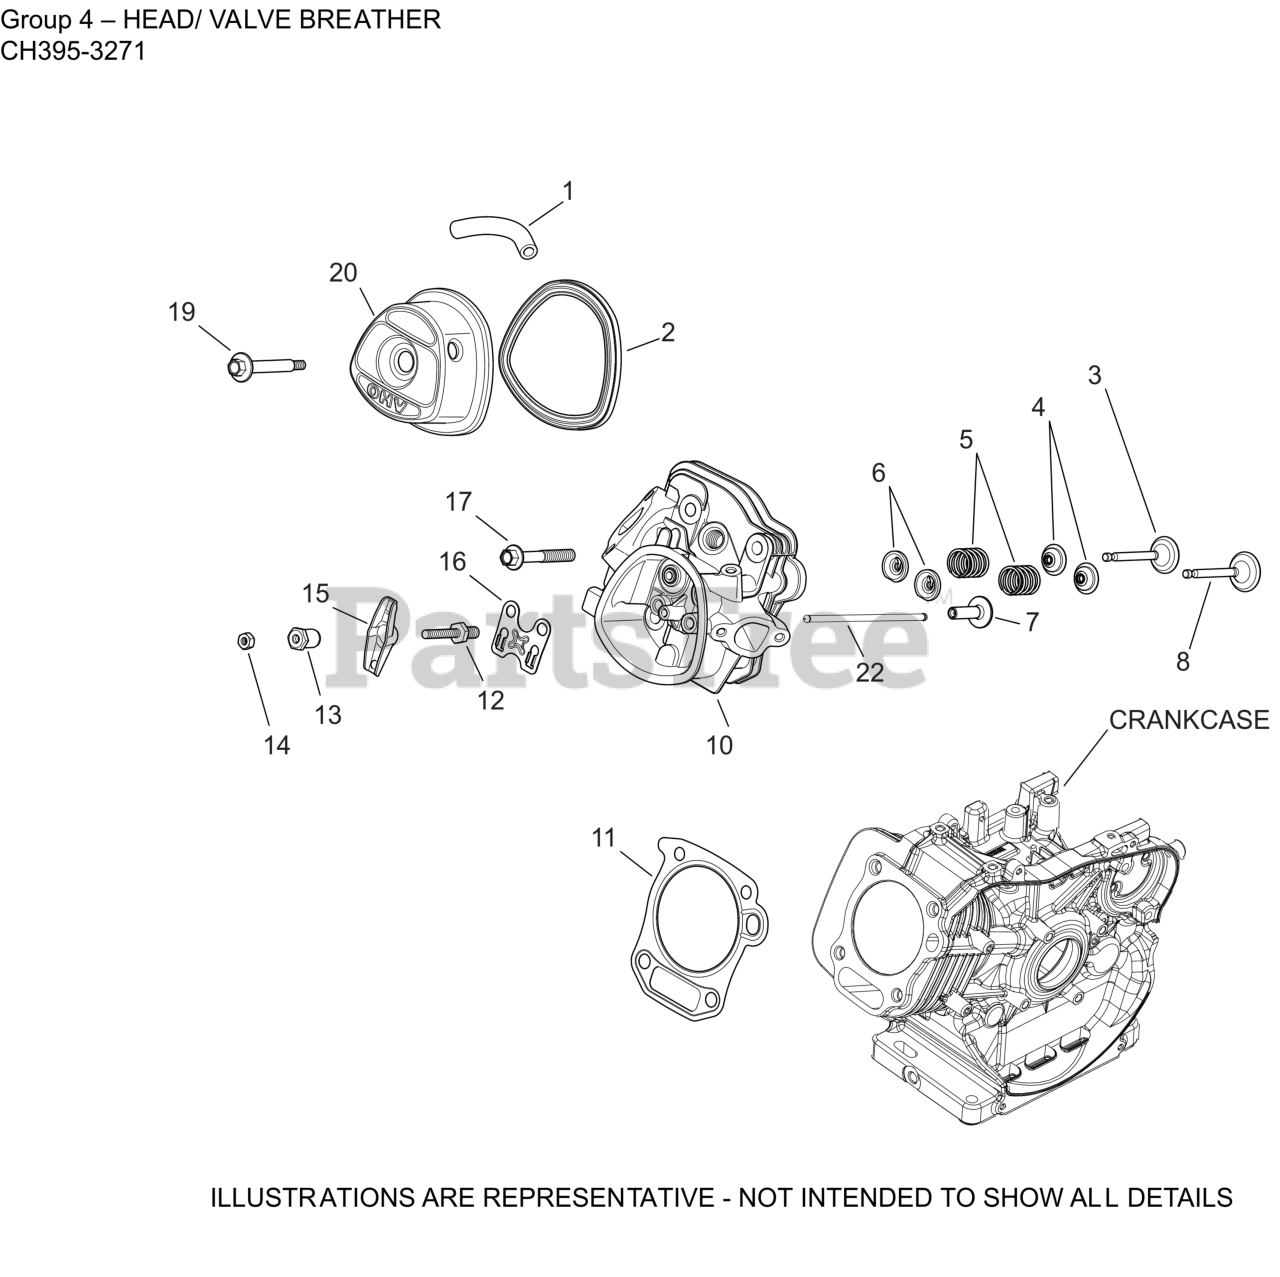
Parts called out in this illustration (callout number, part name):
1	TUBE, BREATHER
2	GASKET, VALVE COVER
3	VALVE, EXHAUST
4	SEAL, VALVE STEM
5	SPRING, VALVE
6	RETAINER, VALVE SPRING
7	LIFTER, VALVE
8	VALVE, INTAKE
10	KIT, HEAD AND VALVE TRAIN
11	KIT, HEAD GASKET
12	STUD, ROCKER ARM-USE 14 072 22-S
13	PIVOT, ROCKER ARM
14	NUT, HEX JAM
15	ARM, ROCKER
16	PLATE, PUSHROD GUIDE
17	SCREW, HEX FLANGE CYLINDER HEAD
19	SCREW, VALVE COVER SEAL ASSY
20	KIT, VALVE COVER ASSEMBLY
22	ROD, PUSH
